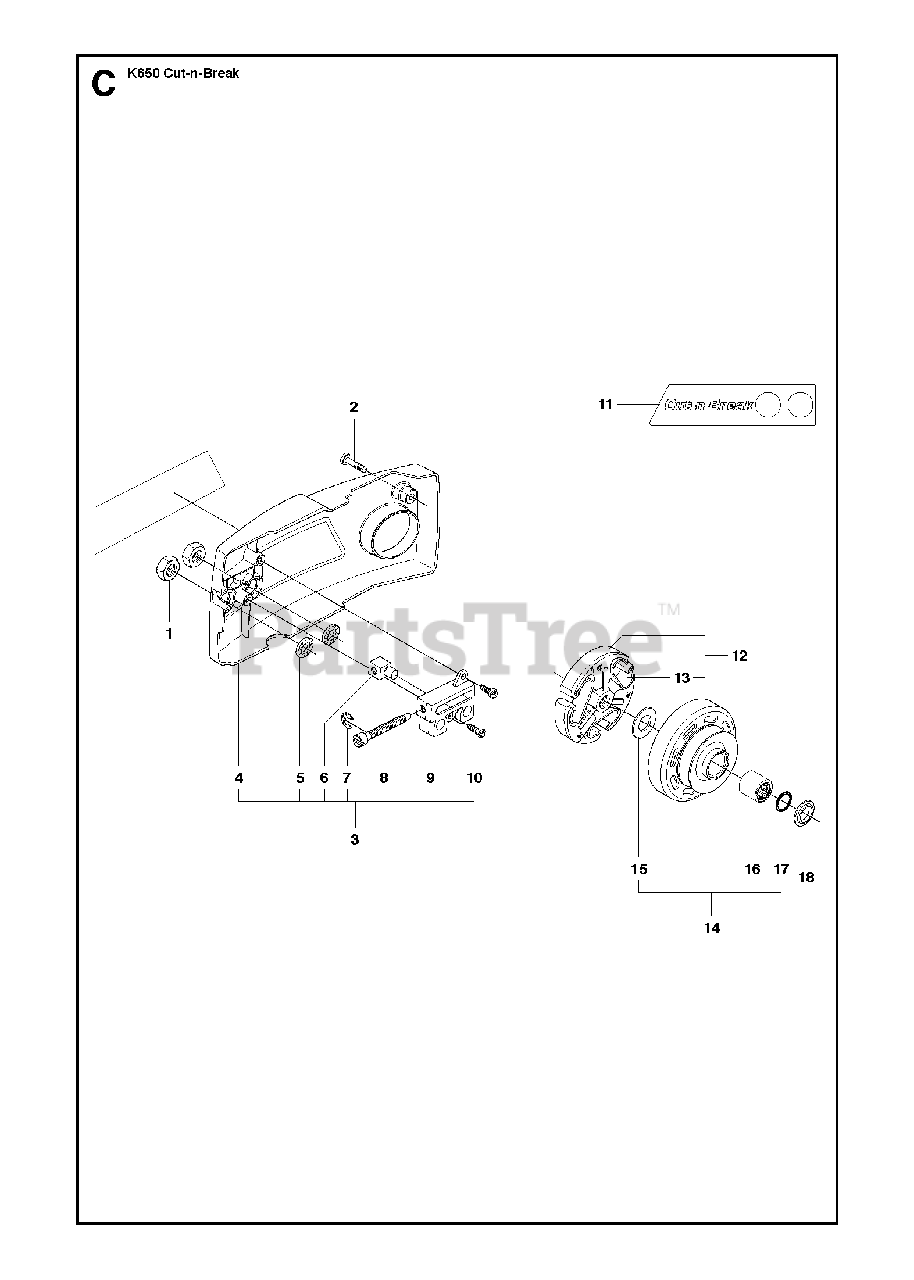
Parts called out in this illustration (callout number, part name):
1	HEXAGON NUT
2	SCREW CCRPANMO
3	CLUTCH COVERIncl. 4 - 10
10	SCREW CRPANT
12	CLUTCH ASSYIncl. 13
13	CLUTCH SPRING
14	GEAR WHEELIncl. 15 - 17
16	NEEDLE BEARING
